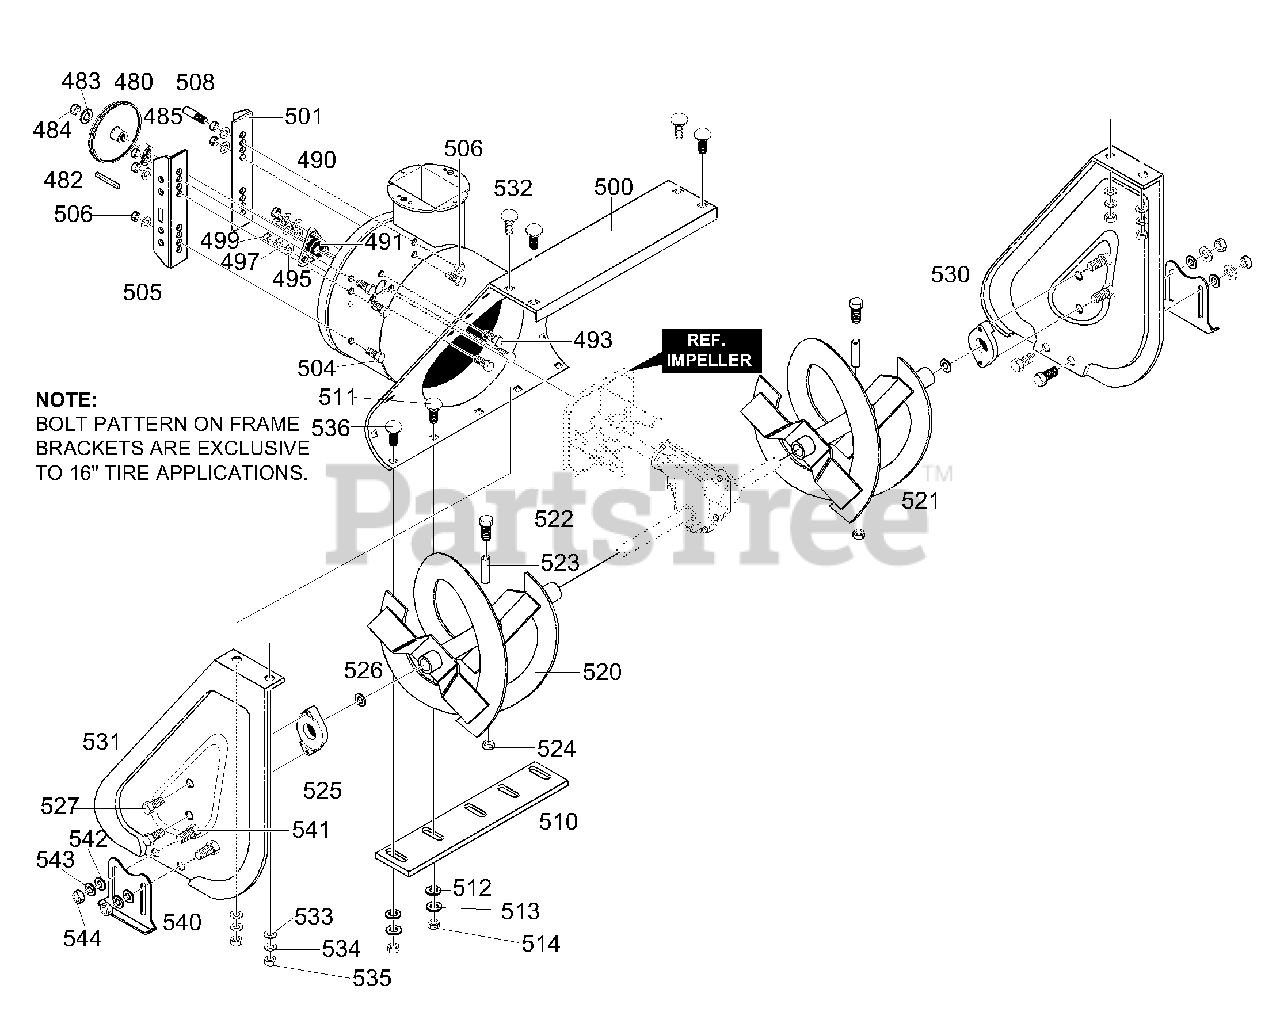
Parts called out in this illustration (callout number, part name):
480	PULLEY, V4L 8.40
482	KEY, SQUARE .18SQX.88LG
483	FLATWASHER, .53X1.00X.063
484	NUT, 1/2-20 REGHXCTRLK
485	SPACER, SLEV .676X1.00X.53
490	RETAINER, BALL
491	BRING, BALL 6203-2AA-C3
493	SCREW 5/16-18X.75
495	FLATWASHER .344X.69X.065
497	WASHER, HVSPTLK .328X.60X.09
499	NUT, 5/16-18 REGHEX
500	HOUSING, ASSY 27/12
501	BRACKET & NUTS ASSY
504	SCREW 3/8-16X.75
505	WASHER, RGSPTLK .393X.68X.10
506	NUT 3/8-16 REGHEXCTRLK
508	STUD, BRAKE ARM
510	BLADE, SCRAPER 27"
511	BOLT, 5/16-18X.75 CARR.
512	FLATWASHER .344X.69X.065
513	WASHER, SPTLK .328X.60X.09
514	NUT, 5/16-18 REGHEX
520	AUGER, ASSY LH 25"
521	AUGER, ASSY RH 25"
522	SCREW 1/4-20X1.75
523	SPACER, SLEV .250X.47X.20
524	NUT 1/4-20 REGHEXCTRLK
525	AUGER SHAFT BEARING
526	FLATWASHER 1.005X1.31X.035
527	SCREW, 5/16-18X.75 WAHHTAP
530	PLATE, AUGER HSNG LH
531	PLATE, AUGER HSNG RH
532	BOLT 5/16-18X.75 CARR.
533	FLATWASHER .344X.69X.065
534	WASHER, HVSPTLK .328X.60X.09
535	NUT, 5/16-18 REGHEX
536	BOLT, 5/16-18X1.00 CARR.
540	SKID, HEIGHT ADJUST
541	BOLT, 5/16-18X.75 CARR.
542	FLATWASHER .344X.69X.065
543	WASHER, HVSPTLK .31X.58X.08
544	NUT, 5/16-18 REGHEX
